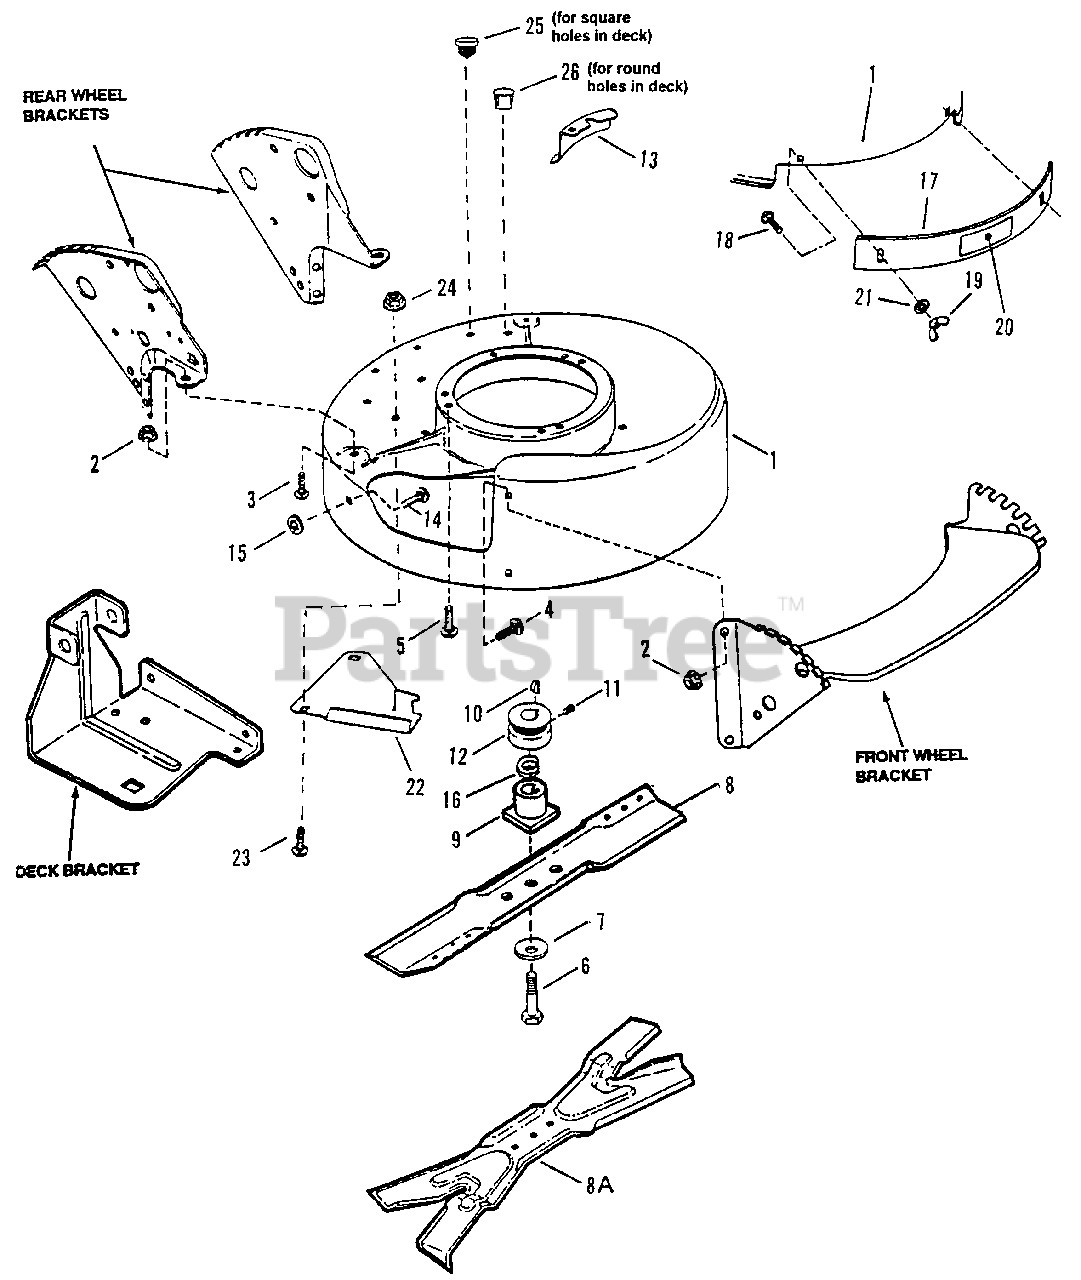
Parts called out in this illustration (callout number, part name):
1	DECK, Mower
2	NUT, 5/16-18 Hex Flange Lock, Grade 5
3	BOLT, 5/16-18 x 1/2" Short Neck Carriage (Gr. 5)
4	BOLT, Bolt 5/16-18 x 1-1/8" Short Neck Carriage, Grade 5
5	SCREW, 3/8-16 x 1" Self-Tapping (Engine Mounting)
6	SCREW, 3/8-24 x 2" Hex Head Cap, Grade 5 (Self-Prop)
7	WASHER, Cone
8	BLADE, Cutter - Mulcher (Push)
8A	BLADE, Cutter Quad Edge - Ninja (Self-Prop)
9	HUB, Blade Drive 25mm
10	KEY, Woodruff #506 Briggs (Self-Prop)
11	SCREW, 5/16-18 x 5/16" Hex Socket Set (Self-Prop)
12	PULLEY, Engine (25mm I.D. x 2-1/8" O.D.) (Self-Prop)
13	SHIELD, Belt Opening Cover (Push)
14	BOLT, 5/16-18 x 3/4" Short Neck Carriage, Grade 5
15	RETAINER, 5/16 Bolt
16	SPACER, Blade Hub
17	BAFFLE, Front
18	BOLT, 5/16-18 x 1-3/4" Carriage, Grade.5
19	NUT, 5/16-18 Flange Lock, Grade 5
20	DECAL, Front Baffle
21	WASHER, 5/16" Internal External Tooth Lock
22	BAFFLE, Belt
23	BOLT, 5/16-18 x 1/2" Neck Carriage, Grade 5
24	NUT, 5/16-18 Hex Flange Lock, Grade 5
25	PLUG, 5/16" Square Hole
26	PLUG, 5/16" Hole
